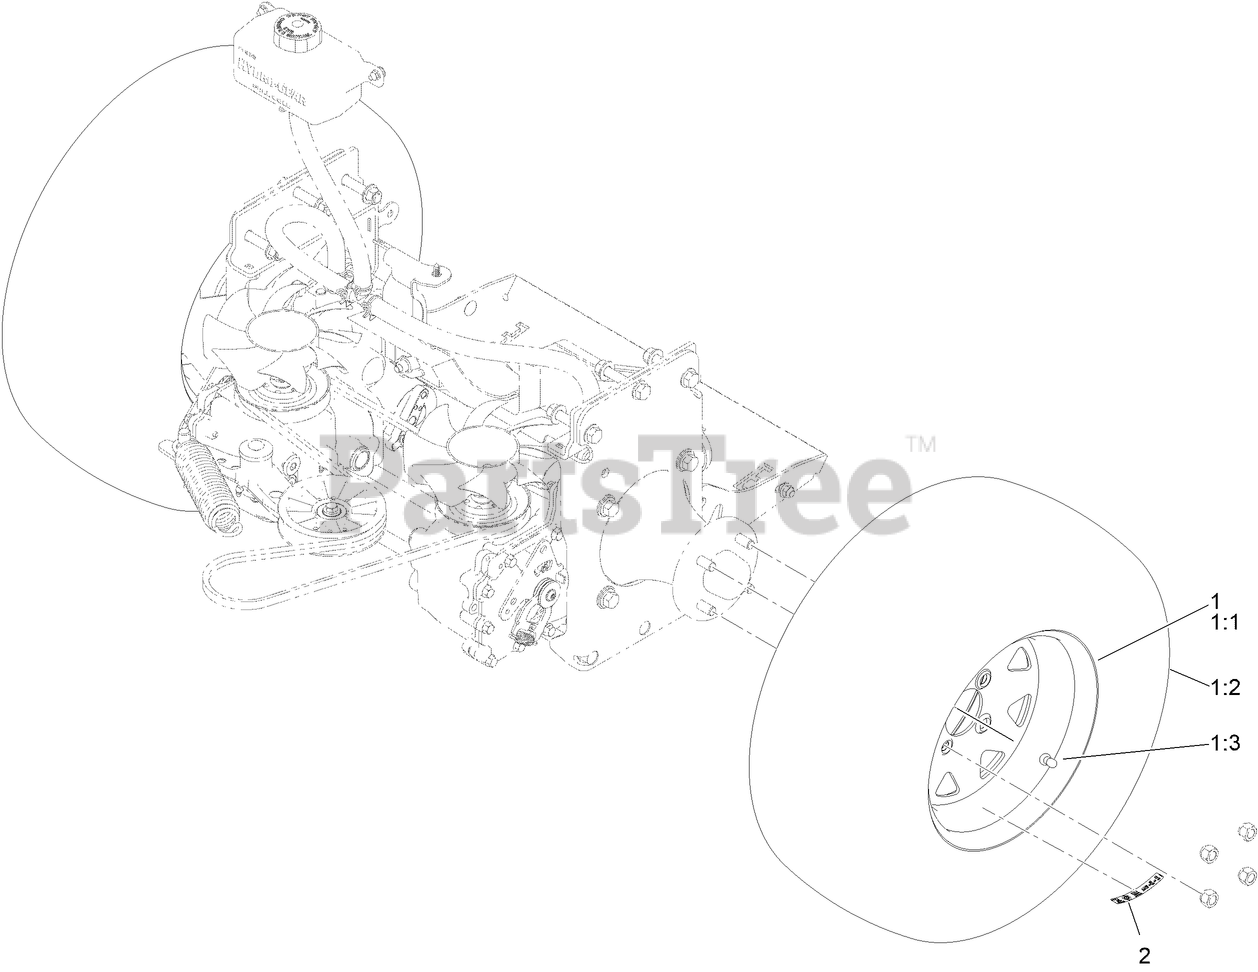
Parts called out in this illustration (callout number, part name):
1	WHEEL AND TIRE ASM
1:1	RIM ASM
1:3	Stem-Valve
2	DECAL-TORQUE, WHEEL HUB LUG
